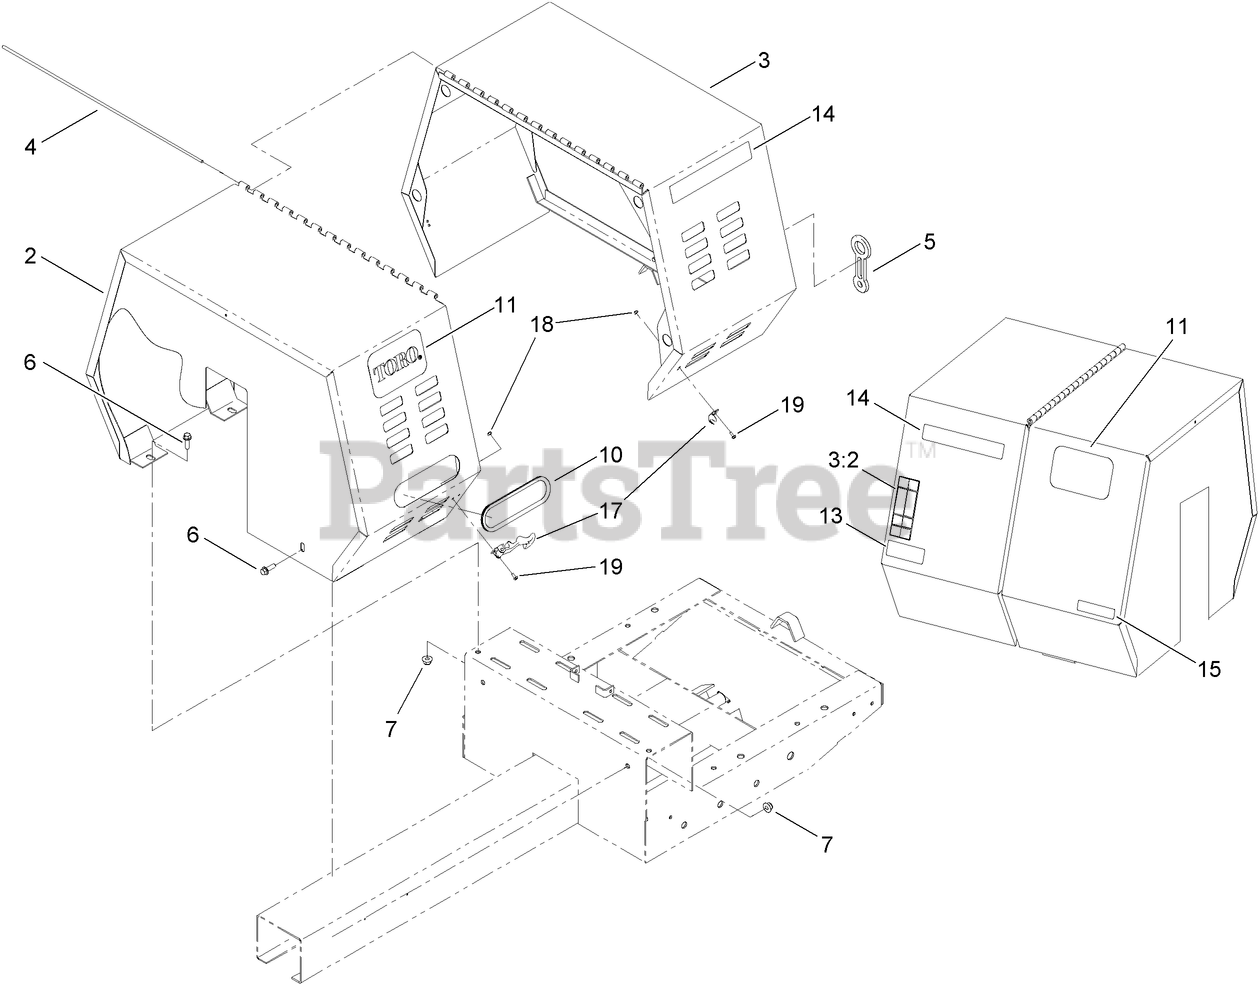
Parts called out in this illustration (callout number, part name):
2	STATIONARY COWL ASM
3	MOVABLE COWL ASM
3:2	DECAL-WARNING
5	LATCH-RUBBER
6	SCREW-HHF
7	NUT-HF, NI
10	TRIM-LID
11	DECAL
14	DECAL-MM-12511H
15	DECAL-ARRESTER, SPARK
17	LATCH-FLEX, DRAW
18	NUT-LOCK, NI
19	SCREW-HWH
